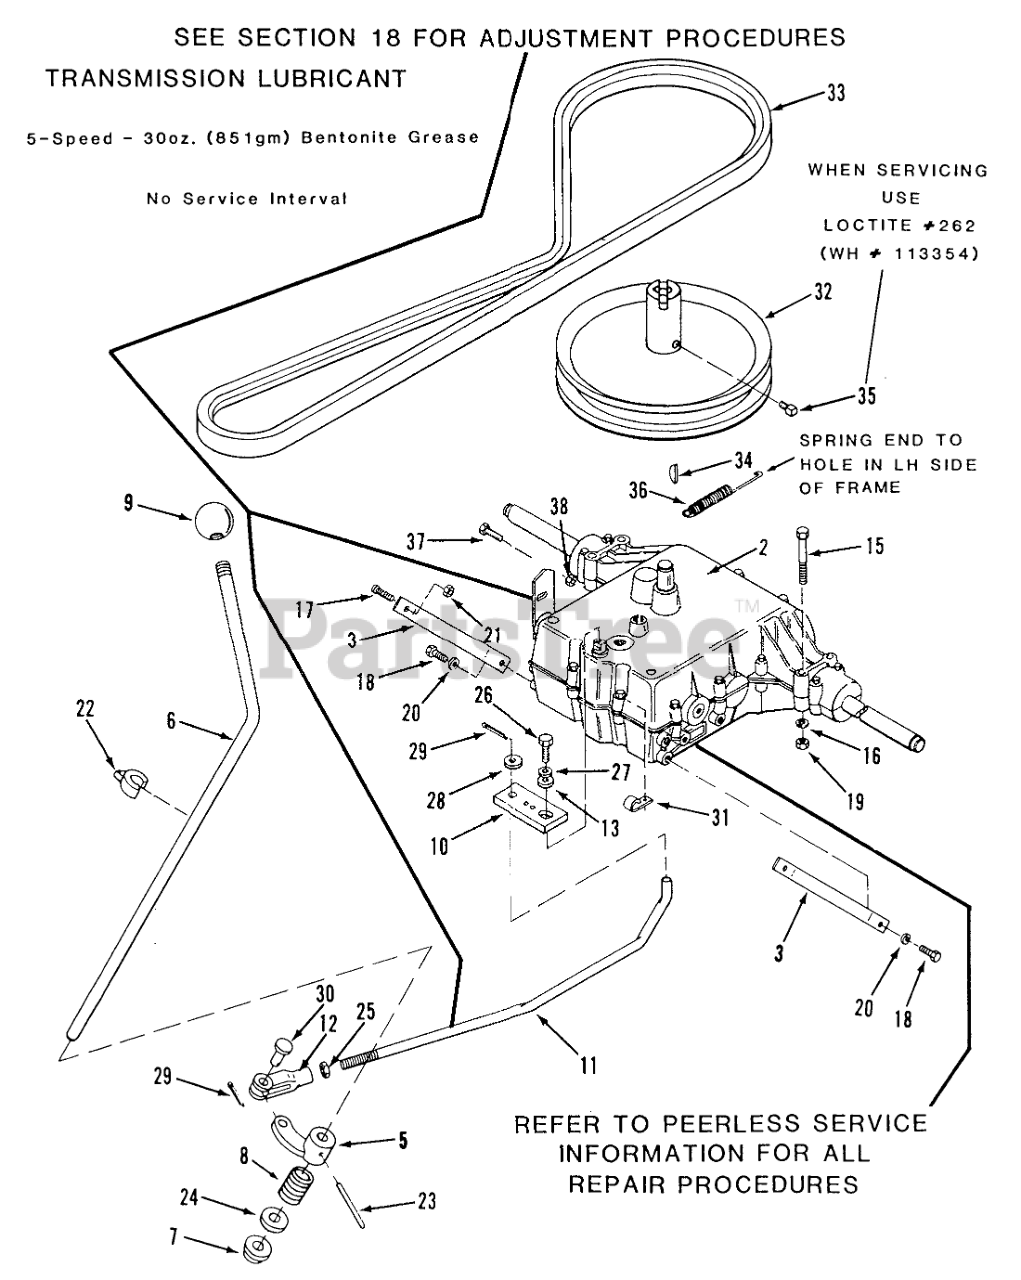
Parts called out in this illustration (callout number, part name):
2	X-REF 78-3340
3	TORQUE-STRAP R
5	ARM SHIFTER B
6	ROD-SHIFT LEVER
7	BUSHING-NYLINER
8	SPRING COMPRESSION
10	ARM-TRANSMISSION 5SP
11	ROD-LINKAGE
12	END-ROD
13	WASHER
15	HHCS
17	CARRIAGE BOLT -4
18	Screw
19	Nut
20	Lockwasher
21	Nut
22	POINTER
23	SPIROL PIN 7/32X21/2
24	SHIM-WASHER
25	Nut
26	Bolt 1/4-28 X 7/8
27	Washer
28	WASHER-SPECIAL
29	Cotter Pin
30	BOLT-SPEC 5/16X1.25
31	J-CLIP
32	PULLEY-TRANS (L)
33	BELT-V
34	KEY-HI-PRO
35	Set Screw
36	SPRING-EXTENSION
37	Bolt
38	Nut
